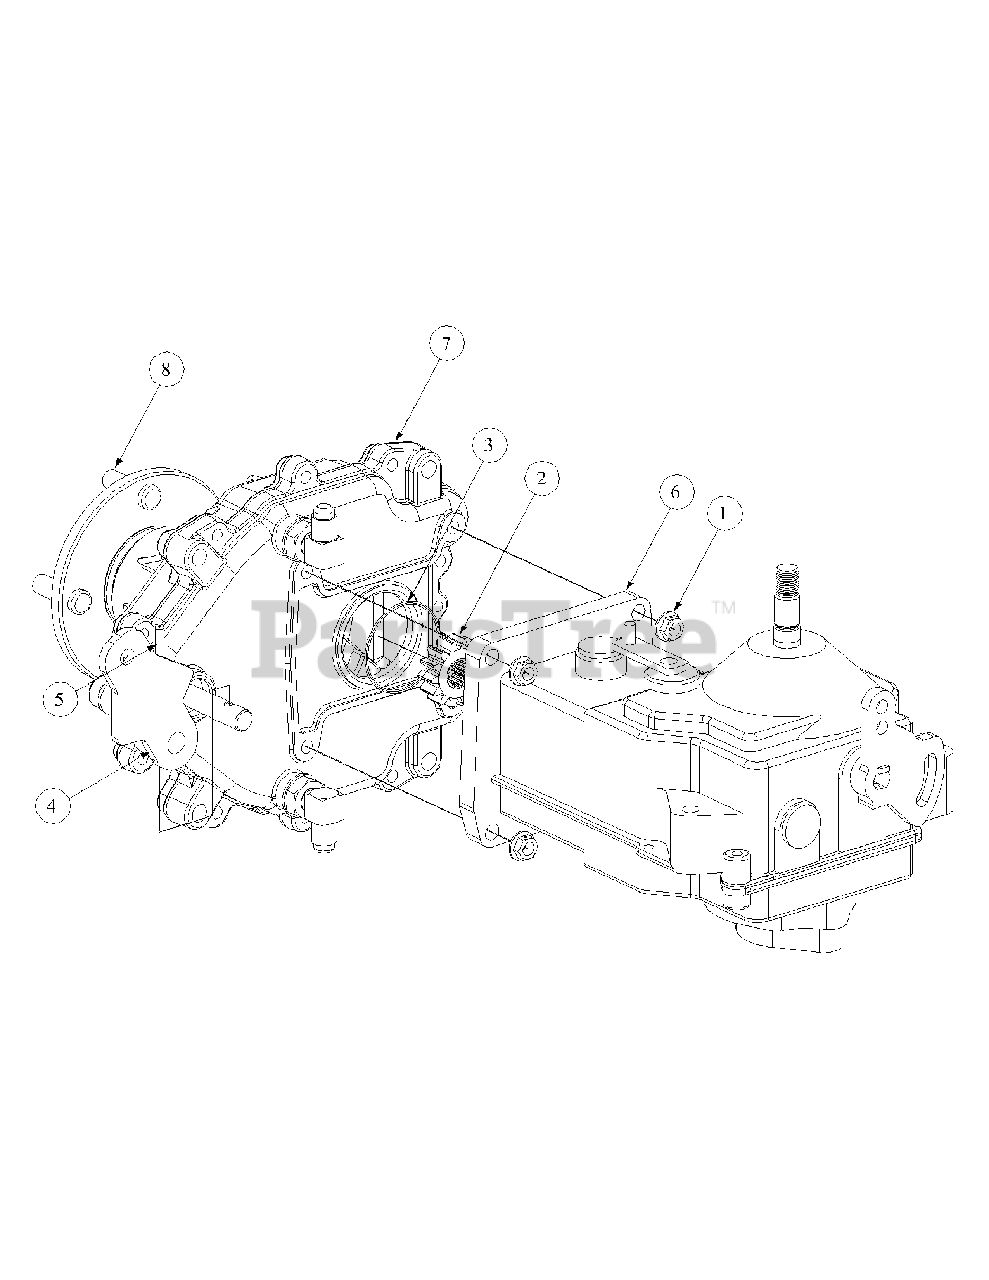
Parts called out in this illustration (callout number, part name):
1	Lock Nut, Hex Flange 5/16-18
2	Gear, Spur, 14T
3	O-Ring, 2.00 x .070
4	Lever, Brake, Park
5	Pin, Spirol, 3/16 x 1.25 HD
6	Pump, Hydro
7	Transmission Assembly
8	Rib Neck Stud, 1/2-20
